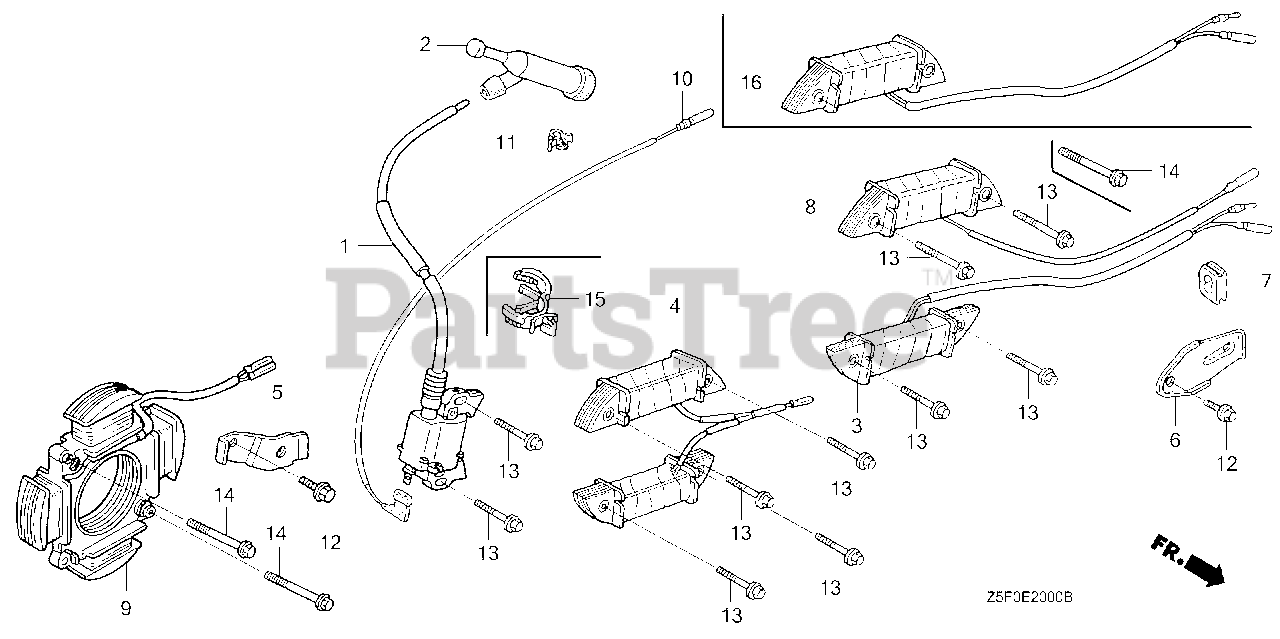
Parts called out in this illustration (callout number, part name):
1	COIL ASSY., IGNITION
2	CAP ASSY., NOISE SUPPRESSOR (NICHIWA Y-EZ RTFM256)
7	GROMMET, WIRE
10	WIRE, STOP SWITCH (370MM)
13	BOLT, FLANGE (6X28) (CT200)
15	CLIP, HARNESS
